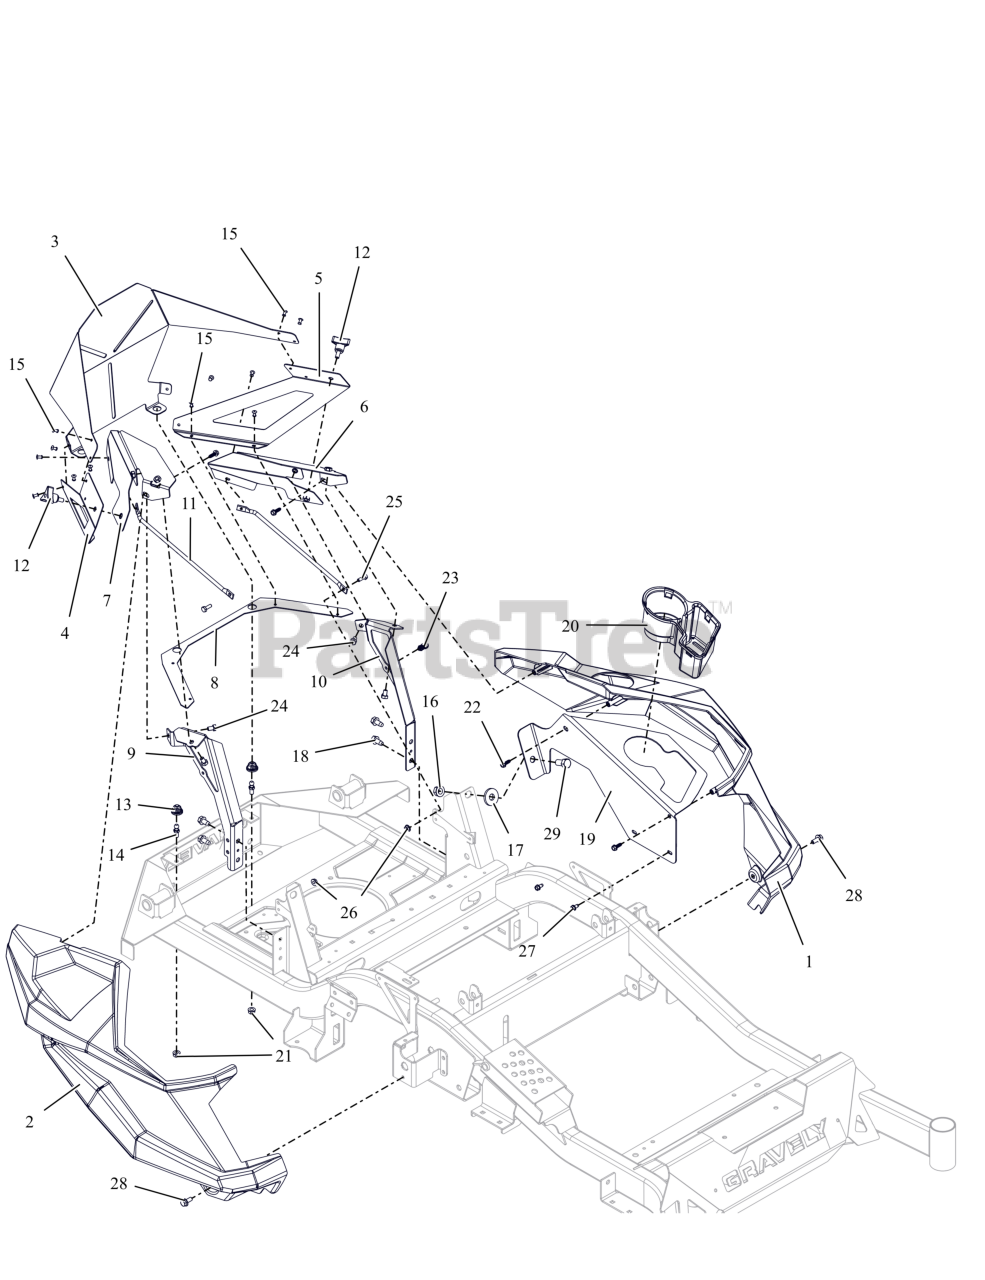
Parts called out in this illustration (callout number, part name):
1	FENDER, LH
2	FENDER, RH
3	WRAP, REAR (BLACK)
4	WRAP, REAR - RH (RED)
5	WRAP, REAR - LH (RED)
6	PANEL, LH (RED)
7	PANEL, RH (RED)
8	STIFFENER, BACK WRAP (RED)
9	BRKT, RH FENDER MTG (RED)
10	BRKT, LH FENDER MTG (RED)
11	ROD, STIFFENER
12	KNOB,WING STUD 5/16-18 X .75
13	GROMMET, 10MM BOLLHOFF
14	STUD- BALL
15	RIVET, #66 STEEL POP PD BLACK
16	NUT-LK-TOP-FLG .500-13 GF ZCC
17	WASHER- FLT .562X1.50X.187 ZCC
18	SCR,TAP .375-16X.75 HWH TR ZCC
19	PANEL, HD CUPHOLDER (RED)
20	HOLDER, CUP
21	NUT,LK-CTR-FLG .31-18 GF ZCC
22	SCR, PLASTITE-HWH 0.25 X 0.75 ZC120
23	CLIP, CABLE GUIDE
24	BLT, HEX .31-18X.50 GR5 ZCC
25	BLT, HEX .25-20X.75 G5 ZCC
26	NUT-LK-CTR-FLG .25-20 ZC120
27	SCR-TAP .25-20X.50 HWH ZCC
28	BLT, SERHFWH 0.312-18X0.75 GR5 ZCC
29	BLT, HEX .50-13X1.00 G5 ZCC
